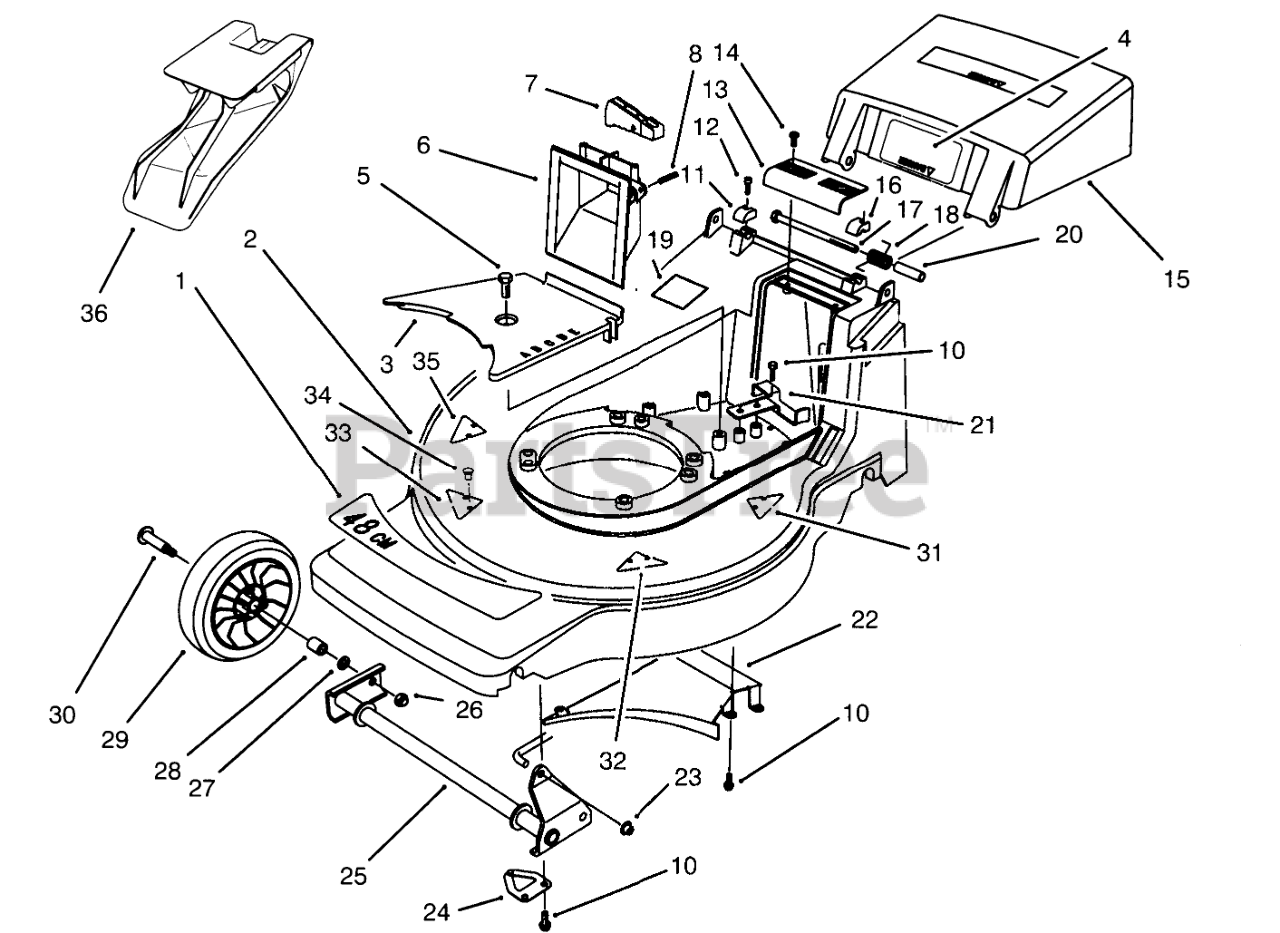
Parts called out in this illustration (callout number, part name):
1	DECAL - DECK 48 CM
2	Housing-48cm (Incl. Ref. #31-35)
3	BELT COVER
4	DECAL-DANGER
5	SCREW-HWHTF
6	GRIP - LOWER
7	TRIGGER - HOC
8	PIN-SPIRAL
10	SCREW-HWH
11	CAP-HINGE BOLT, RH
12	SCREW-HSH
13	GRIP-UPPER
14	SCREW-PPH, PLASTITE
15	Door Discharge
16	CAP-HINGE BOLT, LH
17	SCREW-HH
18	SPRING-DOOR
19	Decal-Noise
20	SPACER-DOOR
21	REAR BELT GUIDE
22	Ramp-Discharge
23	NUT-PUSH
24	SHAFT RETAINER ASM
25	FRONT PIVOT WA
26	NUT-HEX
27	WASHER
28	BUSHING
29	Wheel & Tire Assembly (Incl. Ref. #28)
30	BOLT-WHEEL
31	KICKER
32	KICKER
33	KICKER
34	SCREW-HWHTF
35	KICKER
36	DISCHARGE PLUG
